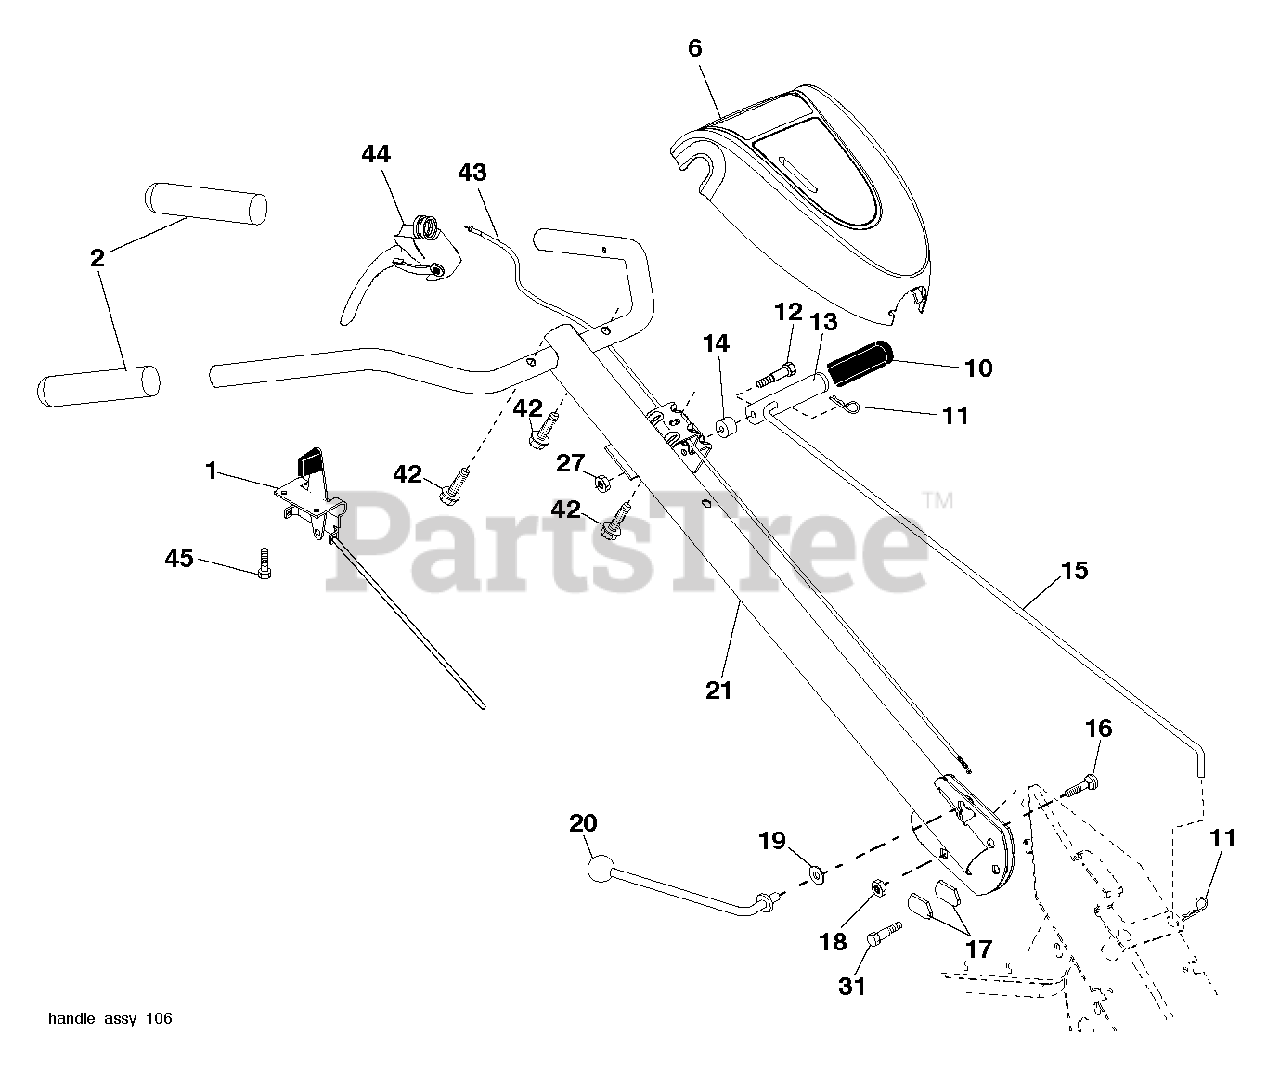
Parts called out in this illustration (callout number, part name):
1	THROTTLE.CONTROL.RT
2	GRIP.1X5.06
11	RETAINER M
12	SHOULDER BOLT ST
13	HANDLE.SHIFT.TILLER
14	GROMMET.RUBBER.CRT.TILLER
15	SHIFT ROD CRT
18	LOCKNUT
19	WASHER CRT
20	LEVER.LOCK.CRT
27	NUT T
42	SCREW.#10 X 0.750.BOS THREAD
45	SCREW.#10 X 0.500
